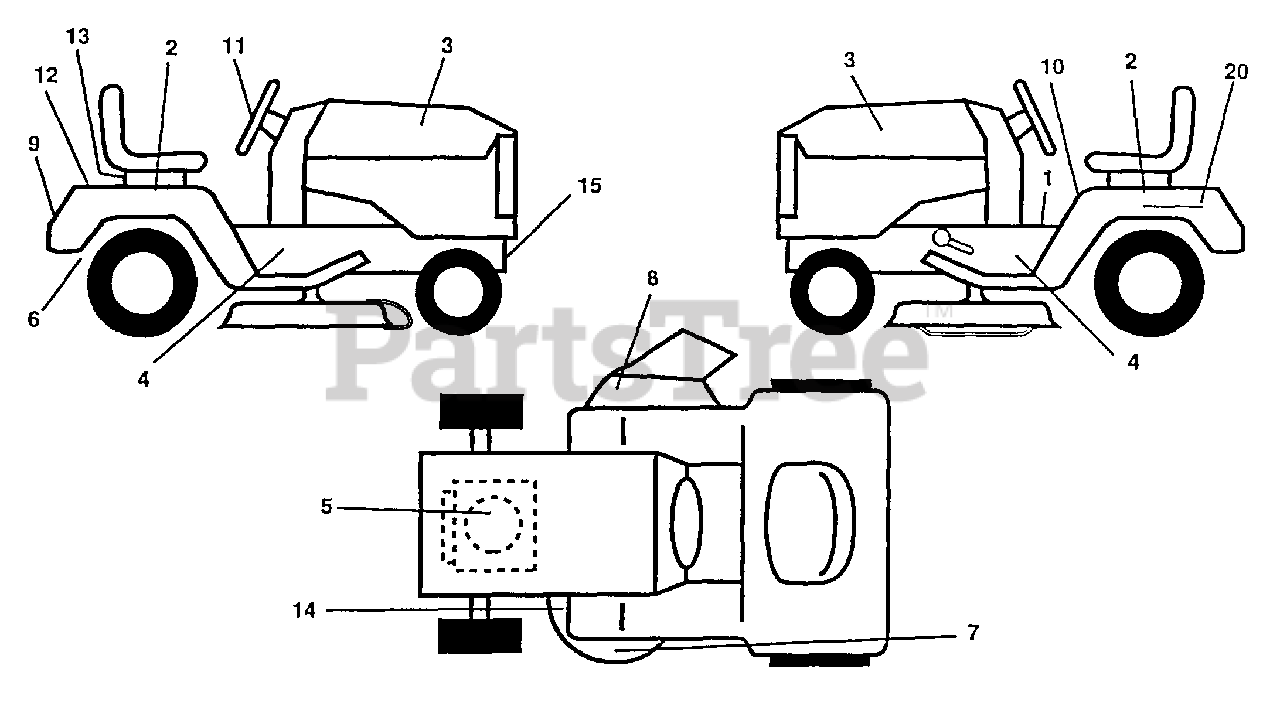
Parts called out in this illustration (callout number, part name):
1	Decal Oper Step Thru E/F
2	Decal Fender Auto Husq
3	Decal Hood LH
4	Decal Chassis 46"/16 HP
5	Decal HP Engine
6	Decal Drawbar Cntrl MVT Hyd LT
7	Decal Mower Enviro
8	Decal Warning Mult-Language
9	Decal Fender Logo
10	Decal Fender Danger E/F
11	Decal Ins Strg Whl
12	Decal Fender Predator
13	Decal Cust Assist Poulan Pro
14	Decal V-Belt Schematic (AYP part number)
15	Decal Front Chassis
20	Decal Bat Dan/Psn
